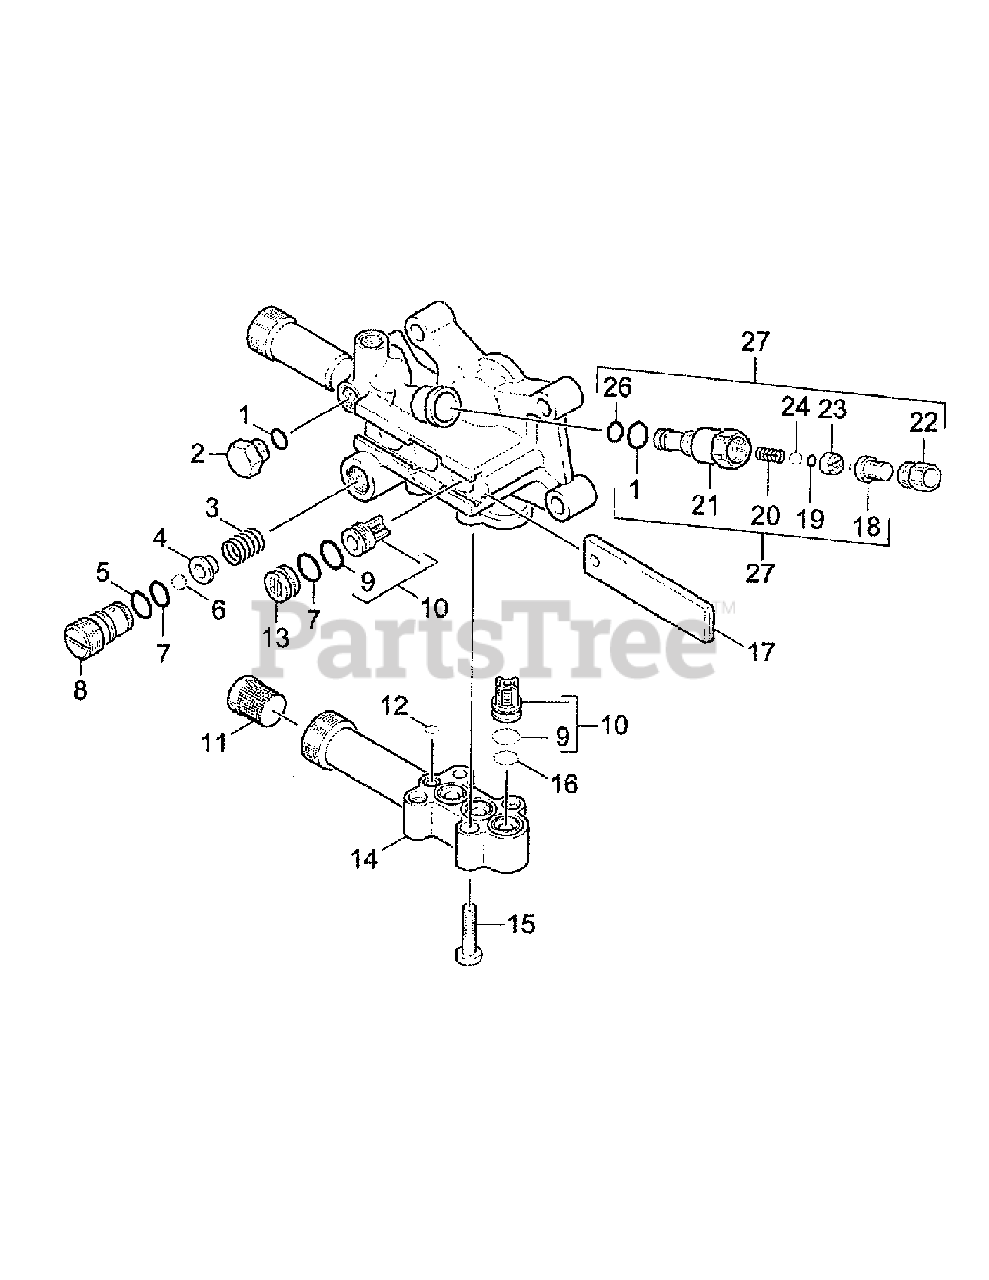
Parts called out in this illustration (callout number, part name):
1	Gasket
2	Closing Screw
3	Helical Spring
4	Valve Disc
5	Gasket
6	Ball
7	Gasket
8	Valve Screw
9	Gasket
10	Valve
11	Strainer
12	Gasket
13	Drain Plug
14	Cover
15	Screw
16	Gasket
17	Plate
18	Valve
19	Gasket
20	Helical Spring
21	Union Screw
22	Closing Screw
23	Washer
24	Ball
26	Gasket
27	Valve
